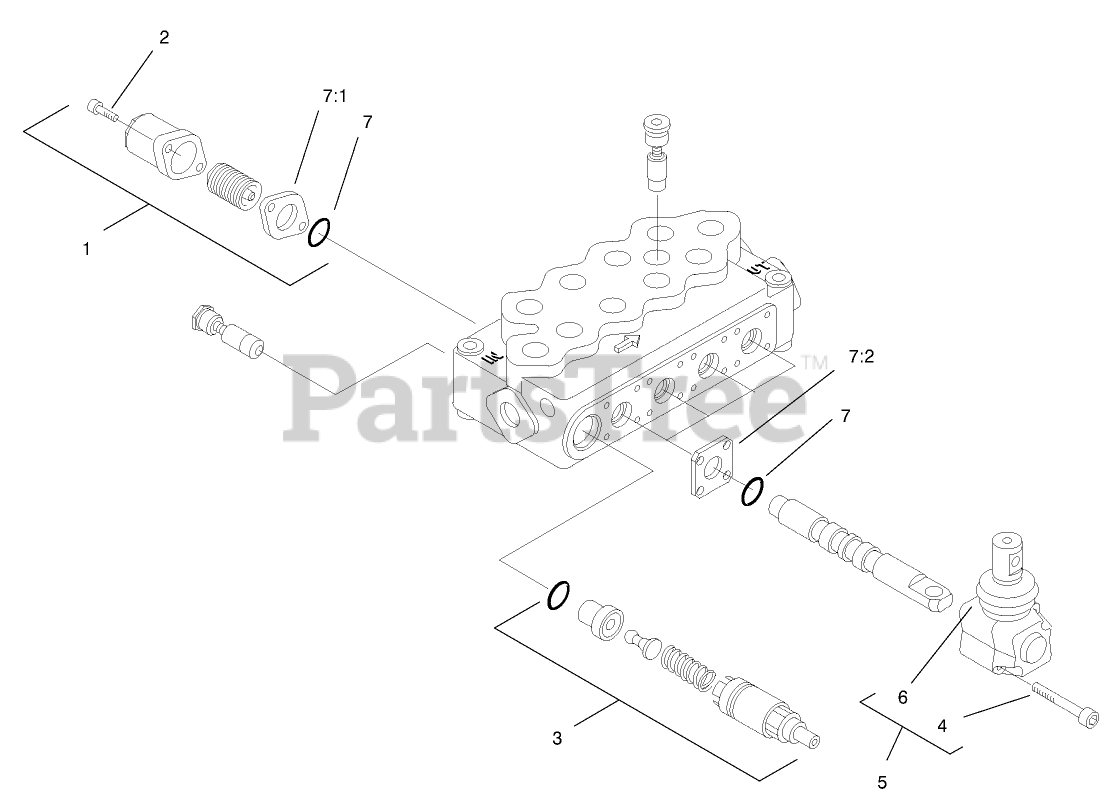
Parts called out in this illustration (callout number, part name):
1	HIGH FORCE SPRING KIT
1	STANDARD SPRING KIT
2	SCREW-CAP, END
3	VALVE-RELIEF
5	OPERATOR ASM
7	SEAL KIT
7:1	GASKET
7:2	GASKET
